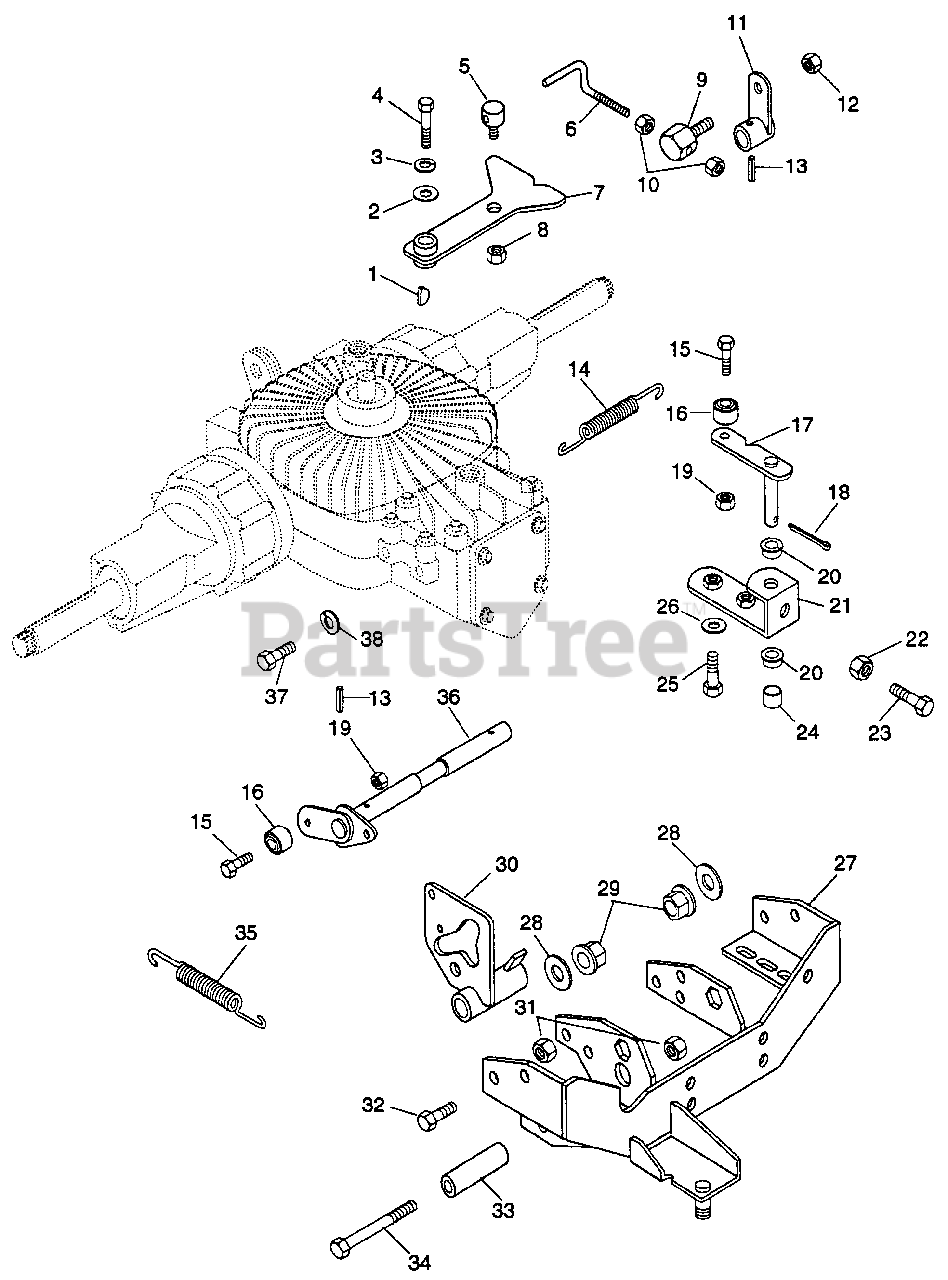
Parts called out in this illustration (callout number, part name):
1	Key, Wdrf 1/8 x 1/2 Hrd #3
2	Wshr-Fl-Stl .312 x .734 x .065 Pl
3	Wshr-Lock .250 Reg
4	Blt-Hex .25-20 x 1.50 Pl Gr 5
5	Adapter
6	Arm
7	Arm, Control 75
8	Nut-Lk .50-13 Esna Thin
9	Rod Pivot
10	Nut-Hex .250-20 ZC
11	Arm & Hub
12	Nut-Lk-Nyl .312-18 Pl
13	Pin, Spring .125 x 1.000
14	Sg-Tens .090 x .96 x 4.0 Wld 23
15	Blt-Hex .25-20 x 1.00 Pl Gr 5
16	Brg Ball Dbl .250 x .638 x .438
17	Pivot Arm
18	Pin-Cotr .125 x 1.00
19	Nut-Lk-Nyl .250-20 Pl
20	Bshg-Flg .500 x .375 x .500 x .687
21	Pivot Bracket
22	Nut-Lk-Ctr .375-16 Typ N
23	Blt-Hex .38-16 x 2.00
24	Bshg-Slv .377 x .624 x .235
25	Blt-Hex .38-16 x .75 Pl Gr 5
26	Wshr-Fl-Stl .406 x .812 x .065 Pl
27	Torque Mount
28	Wshr-Fl-Stl .656 x 1.312 x .095 Pl
29	Bshg-Flg .625 x .875 x .750 x 1 HX
30	Cam
31	Nut-Lk-Nyl .375-16 Pl
32	Blt-Hex .380-16 x .875
33	Spacer
34	Blt-Hex .38-16 x 3.50 Pl Gr 5
35	Sg-Tens .080 x .73 x 3.06 Wld 20
36	Cross Shaft
37	Blt-Hex .31-18 x .625 Gr 5
38	Wshr-Lk .313 x .078 Pl
